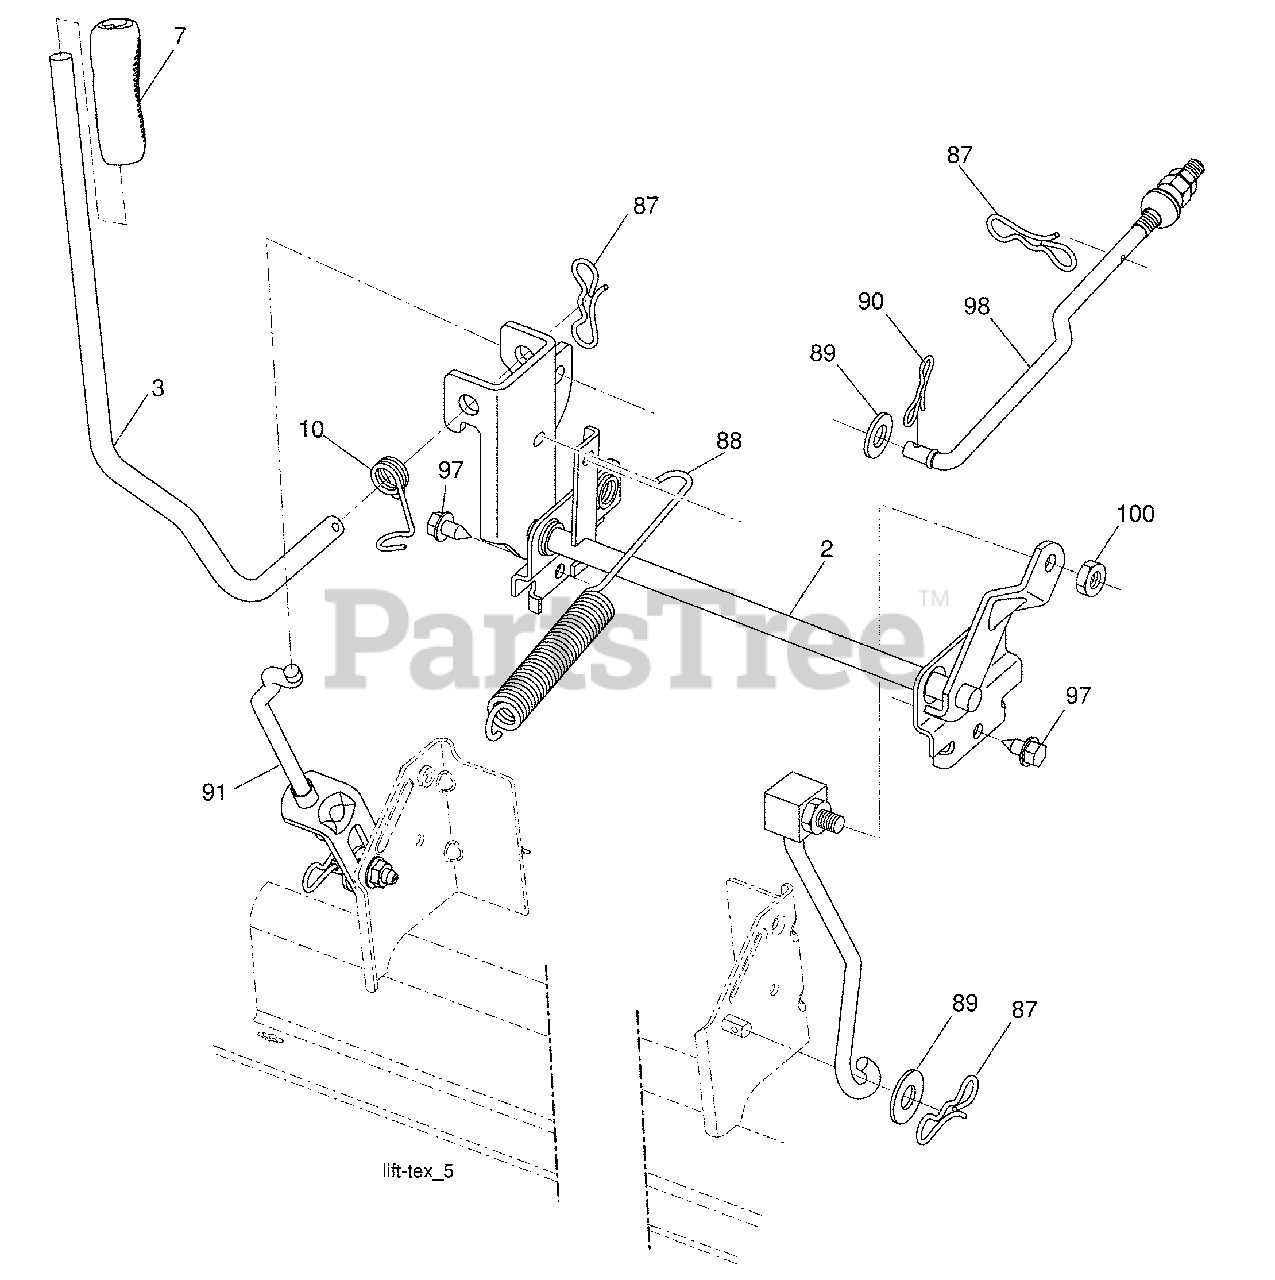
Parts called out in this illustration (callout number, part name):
2	Shaft Asm., Lift
3	Lever Asm., Lift RH
7	Grip, Lever
10	Spring Torsion
87	Pin Cotter 7/16 Bow Tie Lock
88	Spring Lift Assist
89	Washer Clear Zinc
90	Pin Cotter 5/16 Bow Tie Lock
91	Link Lift Susp Mower Rear
92	Bracket Connect Link Lift
95	Bushing Alignment Link Lift
97	Screw 3/8-16 x .75 Smgml Tap/R.Z
98	Link Lift Susp. Front Mower
99	Bushing Spherical Susp Front
100	Nut Hex Jam ASF 7/16-20 unf
